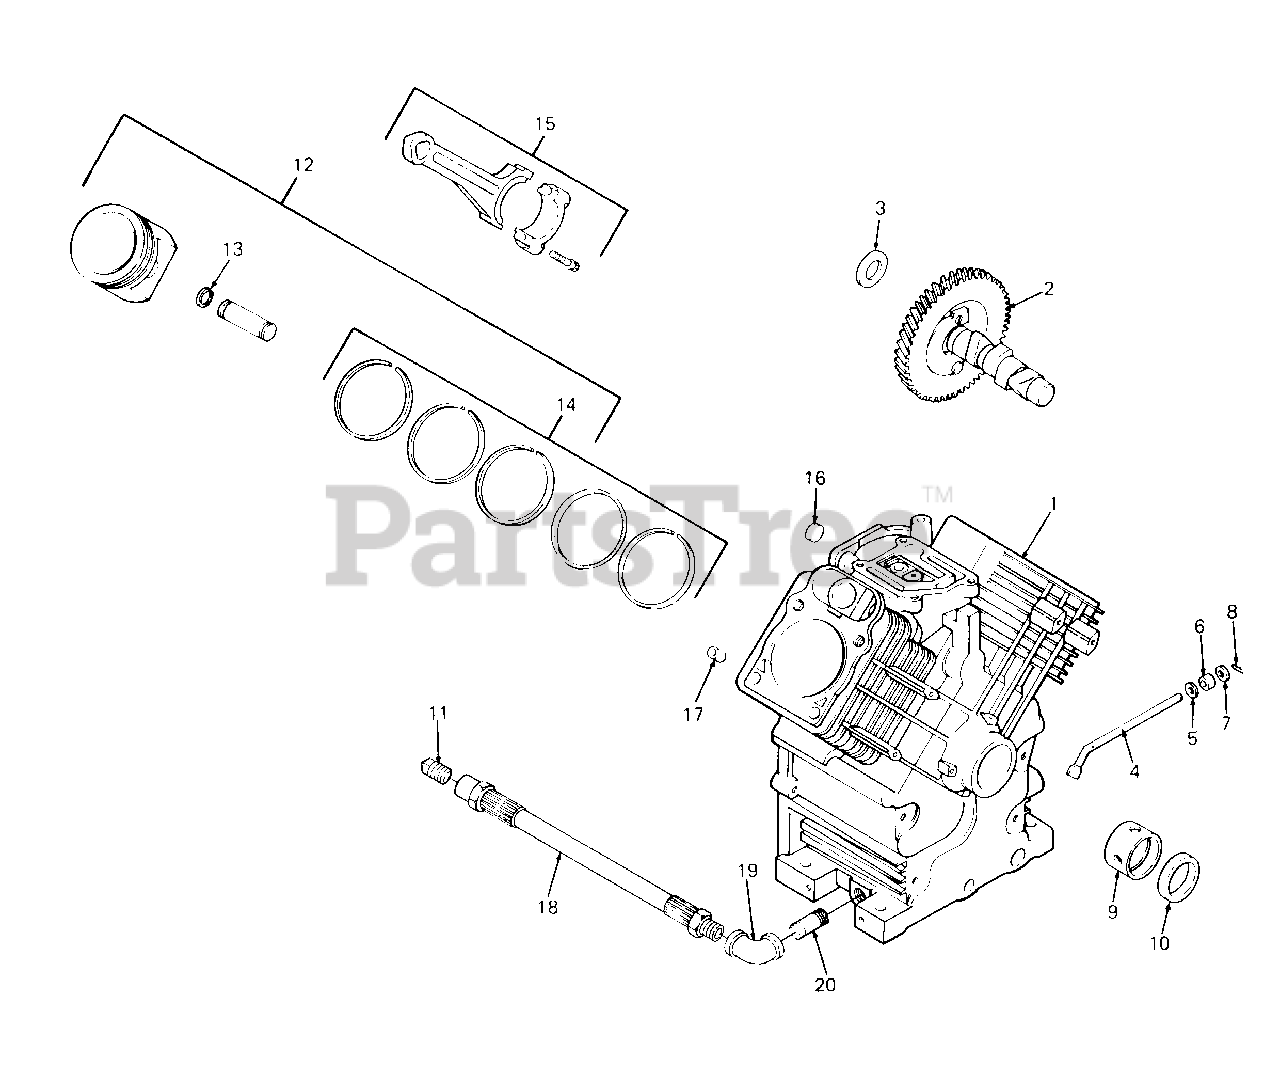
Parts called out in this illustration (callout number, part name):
1	Cylinder Block
2	Camshaft Assembly
3	Shim, Camshaft, .0320
4	Shaft, Governor Cross
6	Seal, Governor Cross Shaft
7	Washer, Plain
9	Bearing, Crankshaft
10	Seal, Oil
11	Plug, Sq Hd Solid, 3/8 NPTF
12	Piston w/Ring Set, Std
13	Retainer, Piston Pin
14	Ring Set, Std
15	Rod, Connecting, Std
16	Plug, Cup
17	Pin, Dowel Locating
18	Hose Assy, Hydraulic
19	Elbow, 3/8
20	Nipple, Pipe, 3/8 X 18 NPT
